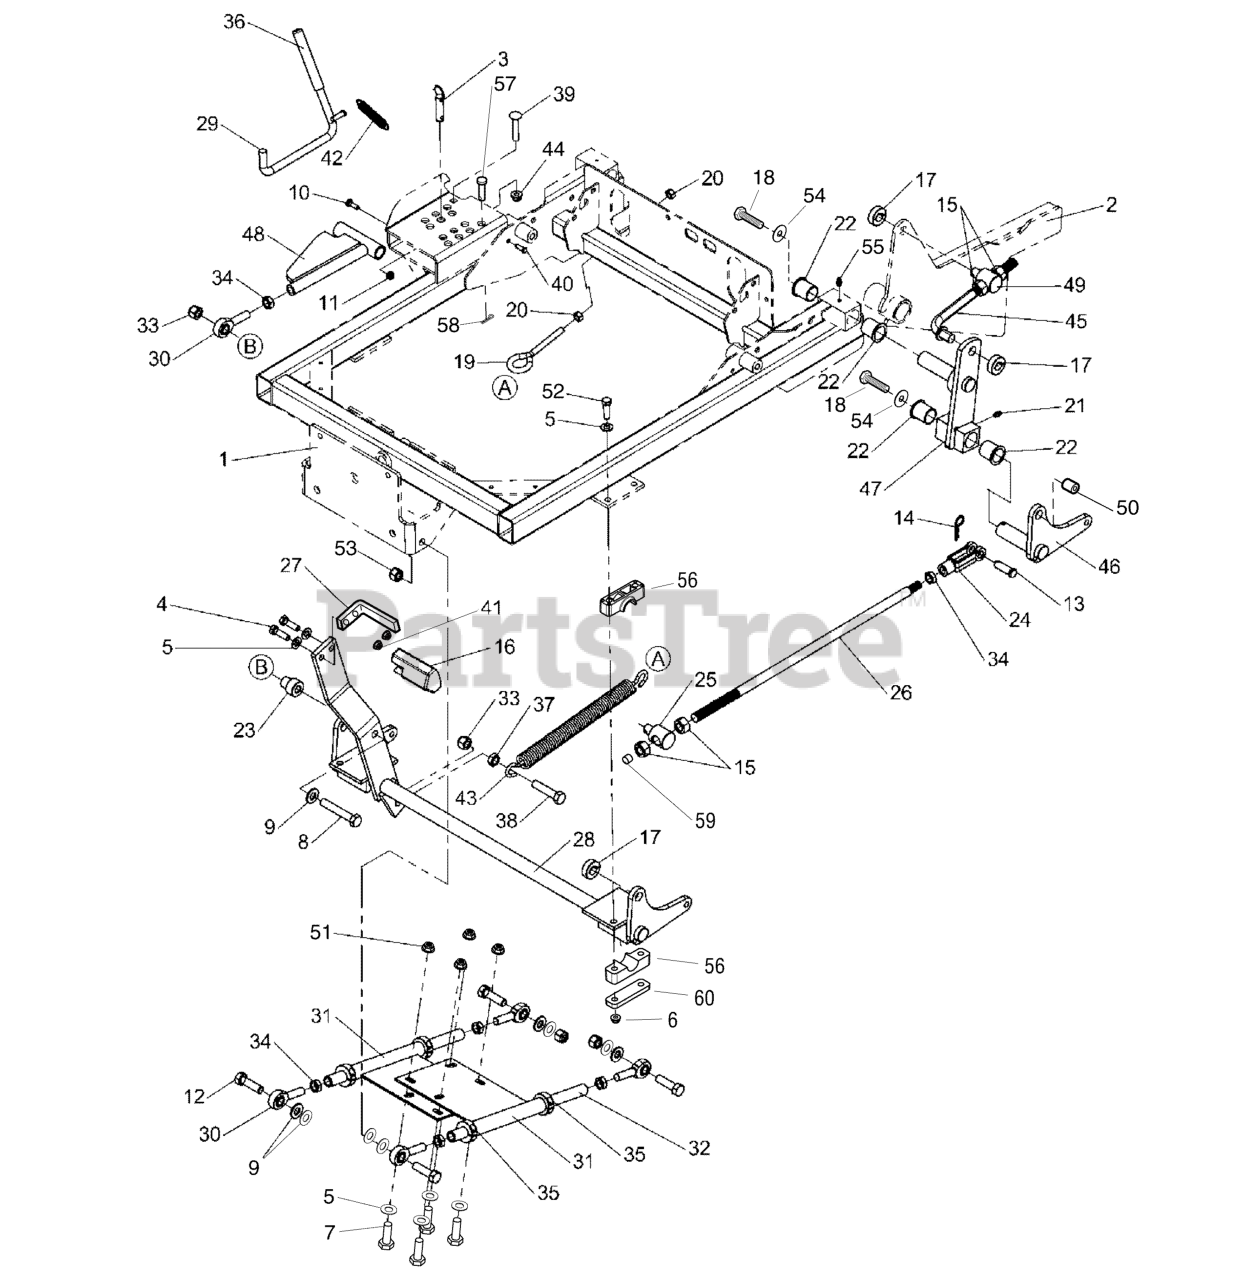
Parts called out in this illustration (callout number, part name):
1	MAIN FRAME
2	MOTOR MOUNT
3	HITCH PIN, 1/2 X 2"
4	BOLT, 3/8-16 X 1-1/4" GD5 CZ
5	WASHER, 3/8 GR. 9 FLAT
6	NUT, 3/8-16 Hex Nylock Flange
7	BOLT, 3/8-16 X 1" GD5 CZ
8	BOLT, 1/2-13 X 3" GD5 CZ
9	WASHER, 1/2 SAE
10	HHCS, 1/4-20 X 0.625, GR5, ZINC/CLEAR
11	NUT, 1/4-20 HEX SERR. FLANGE
12	BOLT, 1/2-20 X 1-3/4" GD8 CZ
13	CLEVIS PIN, 1/2" X 1-1/2"
14	HAIR PIN CLIP
15	NUT, 5/8-11 HEX
16	PEDAL, Rubber
17	COLLAR, 5/8" Split
18	BOLT, 3/8-16 X 3/4, PLT W/PATCH
19	EYE BOLT, 3/8-16 X 5, 2.88THRD, 1EYE, CZ
20	NUT, 3/8-16 Hex
21	GREASE FITTING
22	BUSHING, Flange
23	ADAPTER, CASTER AXLE, CZ
24	CLEVIS , 1/2-20, STEEL
25	SPRING ROD PIVOT
26	DECK ADJUSTMENT ROD
27	PEDAL, FOOT - BLK
28	WELD, DECK LIFT SHAFT - RED
29	WELD, ROD DECK LIFT - BLK
30	BALL JOINT, 1/2-20 Male
31	DECK STABILIZER
32	DECK STABILIZER SHAFT
33	NUT, 1/2-13 HEX NYLON LOCK
34	NUT, 1/2-20 Hex Jam
35	COLLAR, 3/4" Split
36	GRIP
37	NUT, 1/2-13 Hex Jam
38	BOLT, 1/2-13 X 2-1/4" GD5 CZ
39	CARRIAGE BOLT, 3/8-16 X 2"
40	PIN, CLEVIS, 1/4 X 7/8, PLATED
41	NUT, 3/8-16 HEX NYLON LOCK
42	SPRING, Extension
43	DECK LIFT SPRING
44	NUT, 3/8"-16 SIDE LOCK
45	DECK LIFT ROD
46	PIVOT,DECK LIFT WELD,LEFT
47	REAR DECK LIFT, LH
47	REAR DECK LIFT, RH
48	DECK ADJUST LINK
49	SPRING ROD PIVOT
50	BUSHING, .510 X .625 X .500
51	NUT, 3/8"-16 SERRATED FLANGE
52	BOLT, 3/8-16 X 2-3/4" GD5 CZ
53	NUT, Hex, Nylon Lock, 1/2-20
54	FLAT WASHER, THICK
55	GREASE FITTING 45
56	PIVOT BLOCK, PLASTIC
57	PIN, CLEVIS, 1/2 X 2 YZP
58	PIN, COTTER, 1/8 X 1-1/4
59	CAP, VINYL - .562 X .750 - BLK
60	PLATE, PIVOT BLOCK SUPPORT - BLK
